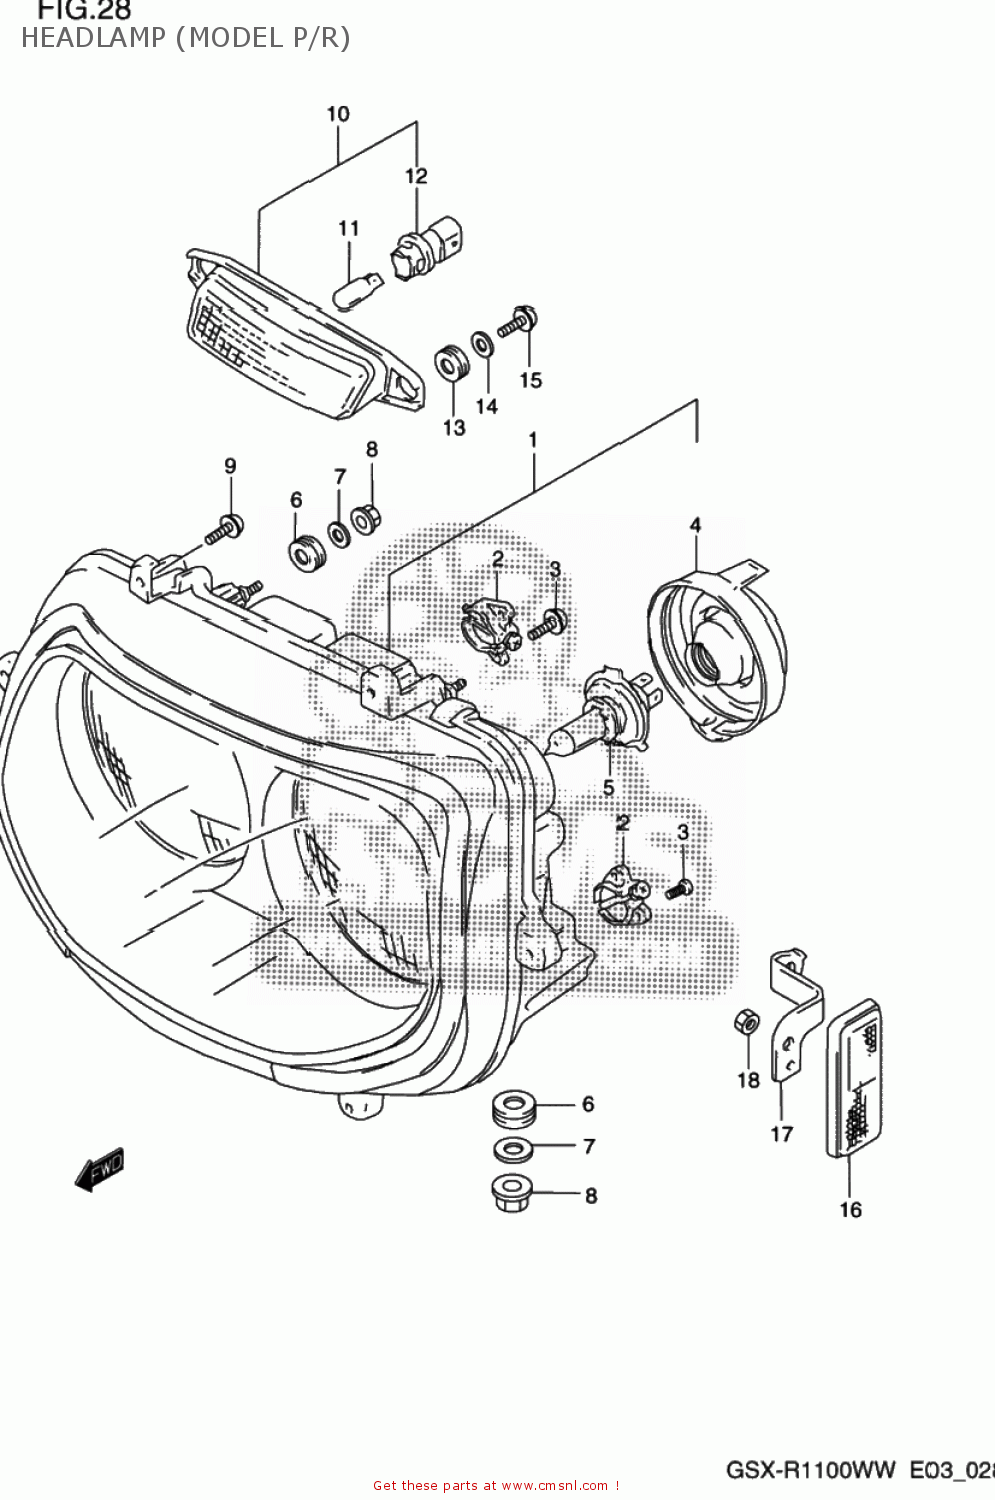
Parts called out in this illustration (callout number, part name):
1	HEADLAMP ASSY
2	GEAR UNIT ASSY,LWR
3	SCREW
4	COVER,SOCKET
5	BULB(12V60/55W,H4)
6	GROMMET
7	WASHER
8	NUT
9	SCREW
10	LAMP ASSEMBLY,FRONT POSITION
11	BULB(12V5W)
12	SOCKET ASSY
13	CUSHION
14	WASHER (4X16X1.2)
15	SCREW
16	REFLEX REFLECTOR,FR SIDE
17	BRACKET,FR SIDE RR,R
18	NUT
